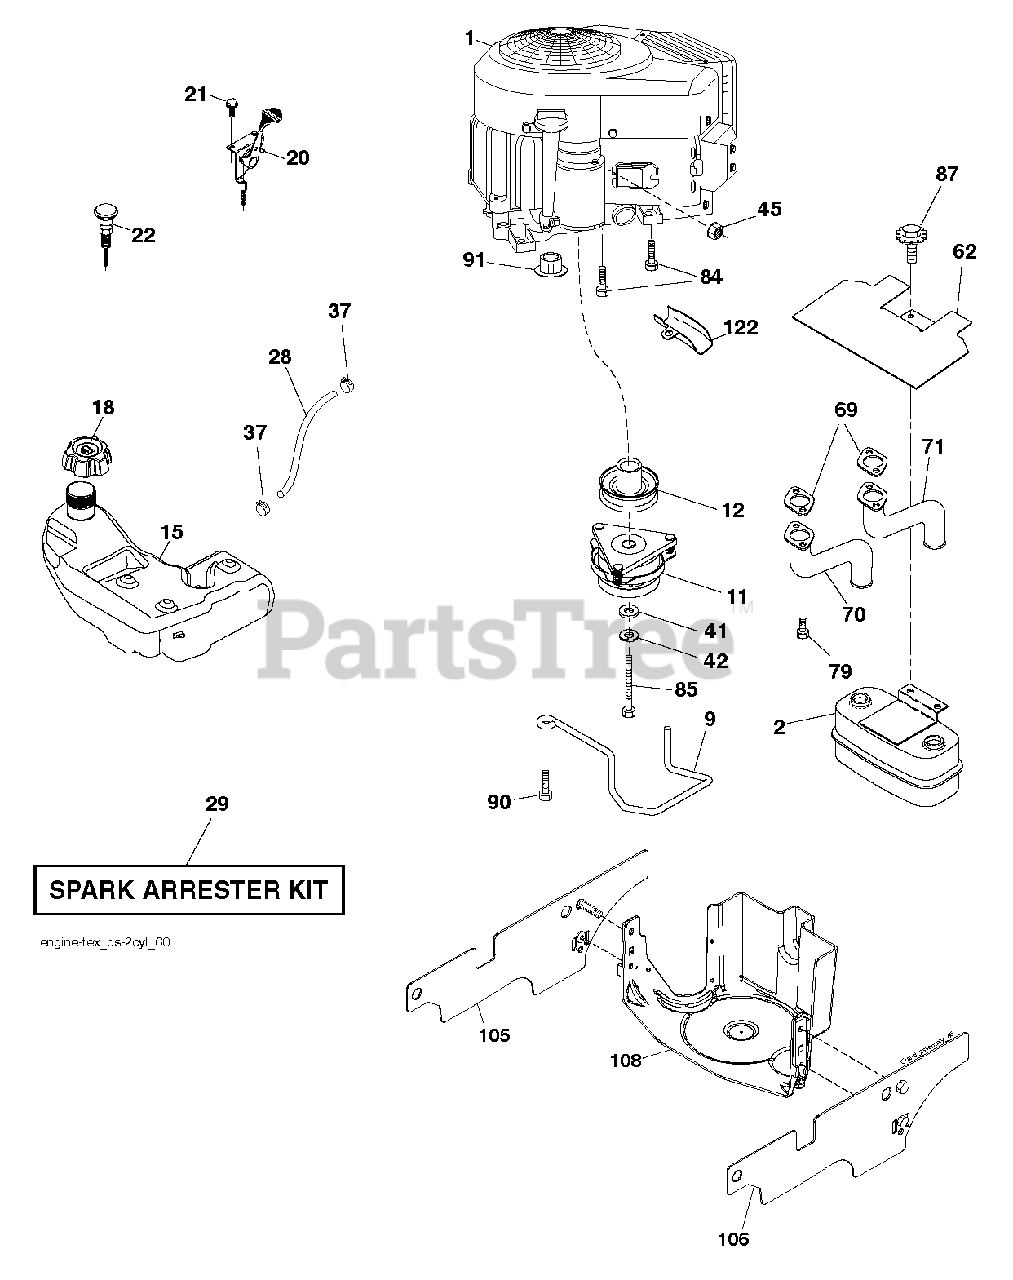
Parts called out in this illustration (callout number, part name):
2	MUFFLER.TWIN.CYL.LOW.TONE
9	KEEPER.BELT.ENGINE.4.2
11	CLUTCH
12	PULLEY.ENGINE.TUFFTORQ
15	TANK.FUEL.4GAL
18	CAP.ASM.FUEL.TANK.3"BLACK
20	THROTTLE CABLE
21	SCREW.#10 X 0.750.BOS THREAD
22	CONTROL CHOKE
28	LINE.FUEL.20
29	ARRESTER SPARK (OPTIONAL)
37	HOSE CLAMP
42	LOCKWASHER
45	NUT
62	RP SHIELD HEAT MUFFLER
69	GASKET.MUFFLER
70	TUBE MANIFOLD LH
71	EXHAUST TUBE RH
79	SCREW.SOCKET.HEAD.5/16-18
84	SCREW.3/8-16
85	BOLT HEX 7/16-20X4-1/4"
87	BOLT, 5/16-18 X 1 3/4
90	SCREW 3/8-16X1
91	BUSHING.1.375OD
122	EXTENSION DRAIN OIL
